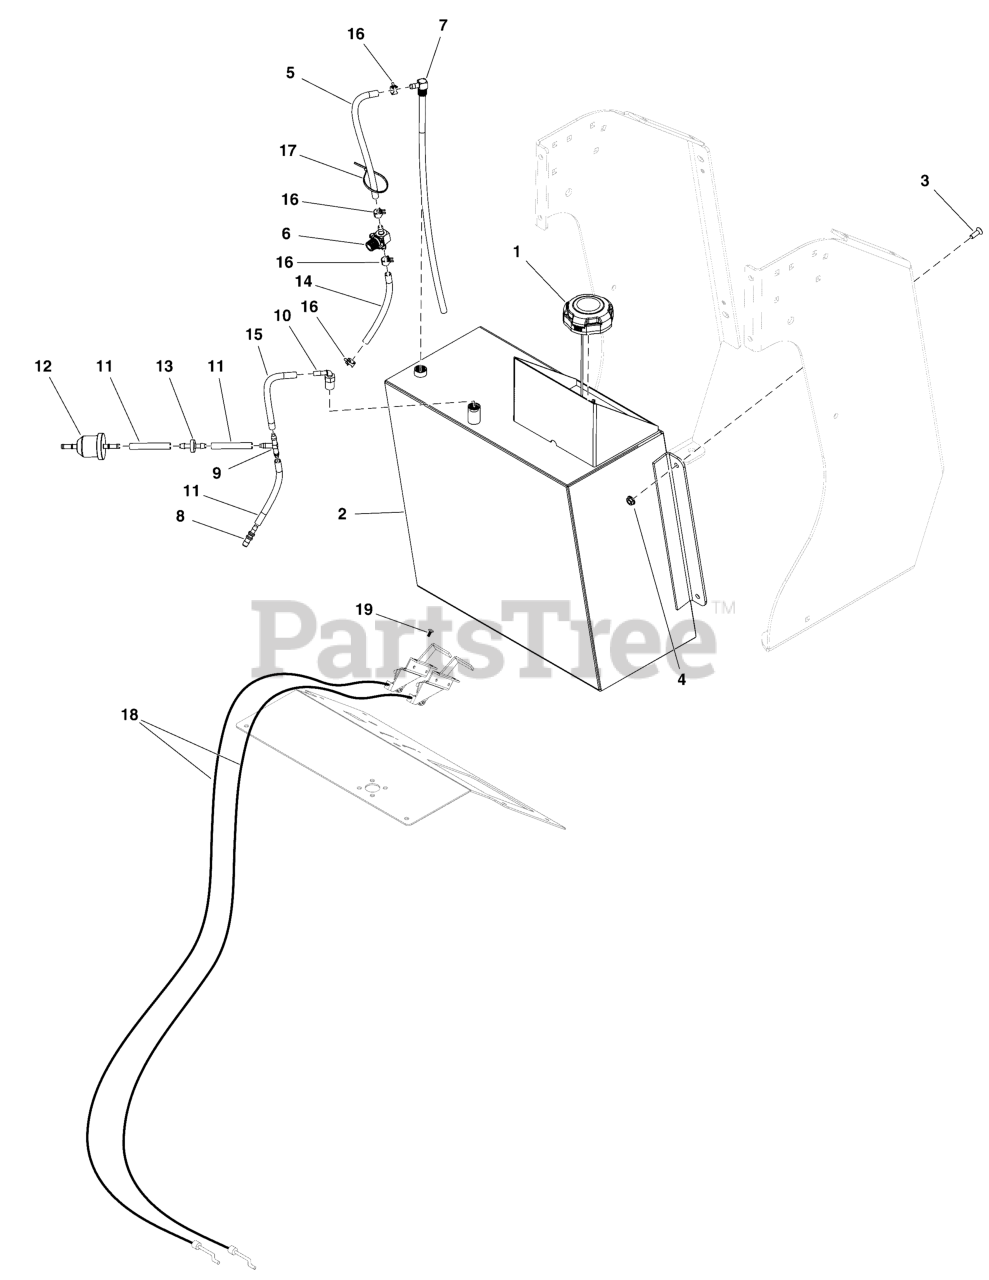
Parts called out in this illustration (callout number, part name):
1	FUEL CAP, 2.0, NON VENTED
2	WELD, FUEL TANK, BLOWER
2	ASSM, FUEL TANK, BLOWER
3	SCREW, 1/4-20 X 3/4, FPHMS, SS
4	NUT, 1/4-20 HEX SERR. FLANGE
5	HOSE, 1/4" FUEL, 6" LONG
6	VALVE, FUEL SHUT OFF
7	PICKUP TUBE ASM,FUEL 16.75
8	FITTING, 1/4X3/16 REDUCER
9	FITTING, 1/4 TEE,BARB TYPE
10	FITTING, 90, 1/4-18 NPT NYLON
11	HOSE, VAPOR, 5MM ID, 2.50 LG
12	FILTER, FUEL
13	CHECK VALVE ASMY
14	1/4" Fuel Line, 4" Long
15	HOSE, VAPOR, 5MM ID, 4.00 LG
16	CLAMP, Hose
17	TIE, SELF-LOCKING, 6"
18	CABLE, THROTTLE/CHOKE
19	SCREW, #10-16 X 1/2, SLF DRLNG, CZ
